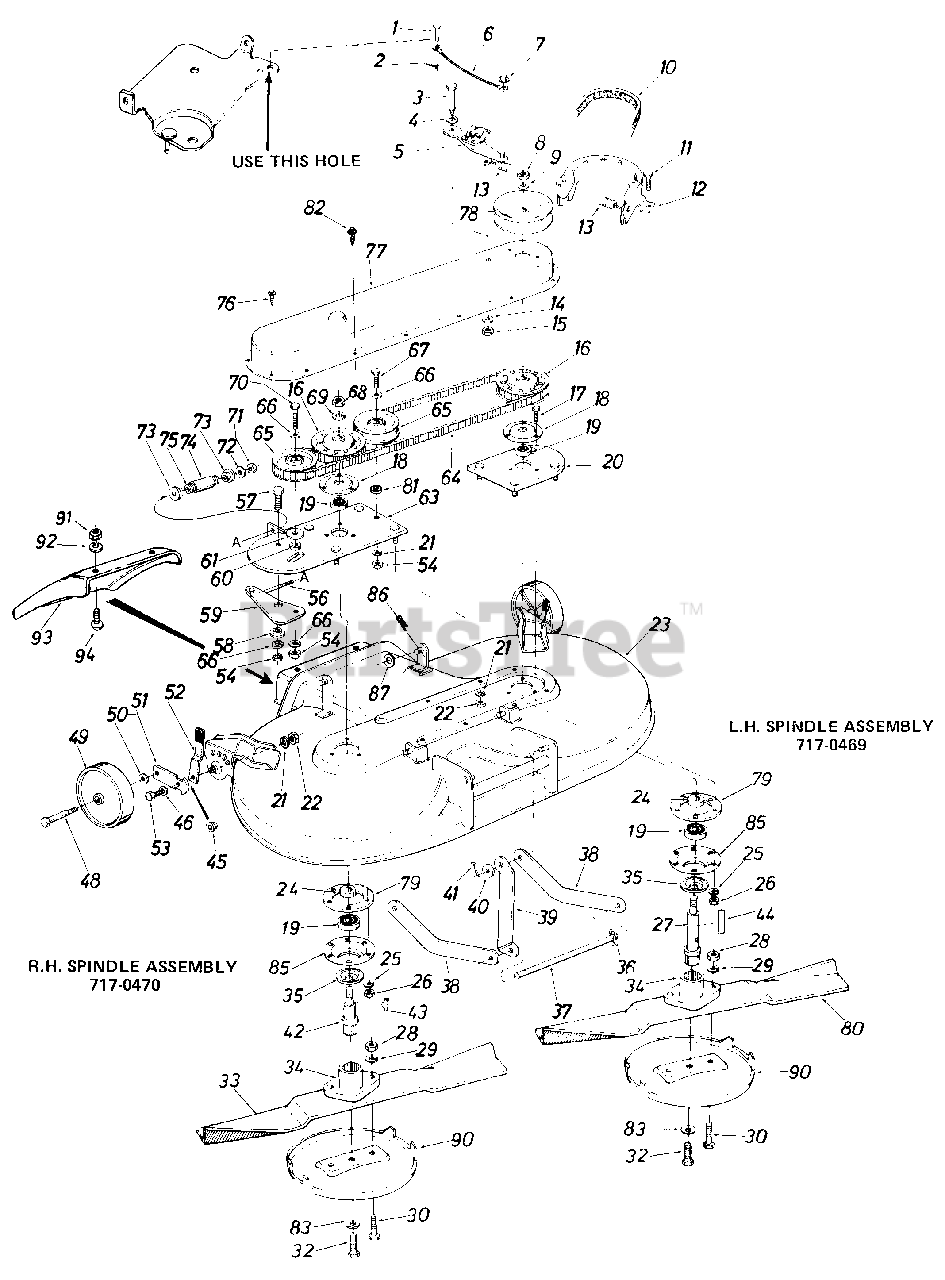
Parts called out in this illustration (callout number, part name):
1	Clevis Pin 1/4" Dia. x 1/2" Lg.
2	Hairpin Cotter 1/4" Dia.
3	Shld. Bolt .437" Dia. x .180" Lg. (5/16-18)
4	Wave Washer 7/16" Scr.
5	Spindle Brake Arm Ass'y.
6	Brake Cable Ass'y.
7	Push Cap 1/4" Stud.
8	Hex Jam Nut 5/8-18 Thd.
9	Bell.-Wash. 5/8" I.D. x 1.25" O.D.
10	"V"Belt
11	Hex Wash. Hd. Self Tap Scr. 1/4-20 x .50" Lg.
12	Belt Guard
13	Extension Spring
14	Bell.-Wash. .340" I.D.
15	Hex Cent. L-Nut 5/16-18 Thd.
16	Sprocket Pulley Ass'y.
17	Hex Bolt 5/16-24 x 1.00" Lg. (Grade 5)
18	Bearing Housing
19	Ball Bearing .787" I.D. x 1.85" O.D.
20	Spindle Plate Ass'y.
21	L.-Wash. 3/8" I.D.
22	Hex Jam Nut 3/8-"4 Thd.
23	44" R.G. Deck Ass'y.
24	Spacer
25	L.-Wash. 5/16" I.D.
26	Hex Nut 5/16-24 Thd.
27	Blade Spindle - L.H.
28	Hex Nut 5/16-24 Thd.
29	L.-Wash. 5/16" I.D.
30	Hex Bolt 5/16-24 x 1.00" Lg.
32	Hex Bolt Cent. L.-3/8 x 24 x88" Lg.
33	22.5" Blade-L.H. Rotation
34	Blade Adapter
35	Bearing Shield
36	Hairpin Cotter
37	Deck Connecting Rod
41	Cotter Pin 3/32" Dia. x 1.00" Lg.
42	Blade Spindle - R.H.
43	Sq. Key 3/16" x 75" Lg.
44	Sq. Key 3/16" x 1.50" Lg.
45	Shoulder Spacer
46	Bell.-Wash. .400" I.D.
48	Shld. Bolt 3/8-16 x 1.41" Lg.
49	Wheel Ass'y. Comp. 6" x 1.38
50	Bell-Wash. 3/8" I.D.
51	Wheel Pivot Bar
52	Spring Lever Ass'y. w/knob
53	Hex Bolt 3/8-24 x 1.25" Lg. Grade 5
54	Hex Cent. L-Nut 3/8-24 Thd.
56	Adjustment Link 5/16-18 x 4-9/16" Lg.
57	Hex Bolt 3/8-24 x 1.00"
58	Shld. Spacer .625" I.D.
59	Belt Idler Brkt.
60	Spacer.380" I.D. x .625" O.D. x .265
61	Fl.-Wash. .38" I.D. x 1.37" O.D. x .125
63	Spindle & Idler Mount Plate Ass'y.
64	HTD Twin Power Belt
65	Fl.-Idler Pulley 3.50" O.D.
66	Bell.-Wash. .38" I.D.
67	Hex Bolt 3/8-24 x 1.75" Lg. (Grade 5)
68	Hex Jam Nut 5/8-18 Thd.
69	Bell.-Wash. 5/8" I.D.
70	Hex Bolt 3/8-24 x 2.00" Lg.
71	Hex Insert L.-Nut5/16-18 Thd.
72	Fl.-Wash. 344" I.D. x 1.125" O.D. x .125
73	Shld. Spacer .625" I.D.
74	Spacer-Adj. Bolt
75	Compression Spring
76	Hex Wash. Hd. Self Tap Scr. 1/4-20 x .50" Lg.
77	Belt Cover
78	Deck Drive Pulley
79	Deck Reinforcement Plate
80	22.5" Blade-R.H. Rotation
81	Fl.-Wash. .38" I.D. x 1.00" O.D.
82	Hex Wash. Hd. Self Tap-Scr. 1/4-20 x .75" Lg.
83	L.-Wash. 3/8" I.D. Heavy Duty
86	Hairpin Cotter
87	Fl.-Wash. 1/2" I.D.
90	Anti Scalp Plate
91	Hex Nut 1/4-20 Thd.
92	L.-Wash. 1/4" I.D.
93	Chute Deflector
94	Truss Mach. Scr. 1/4-20 x .50" Lg.
